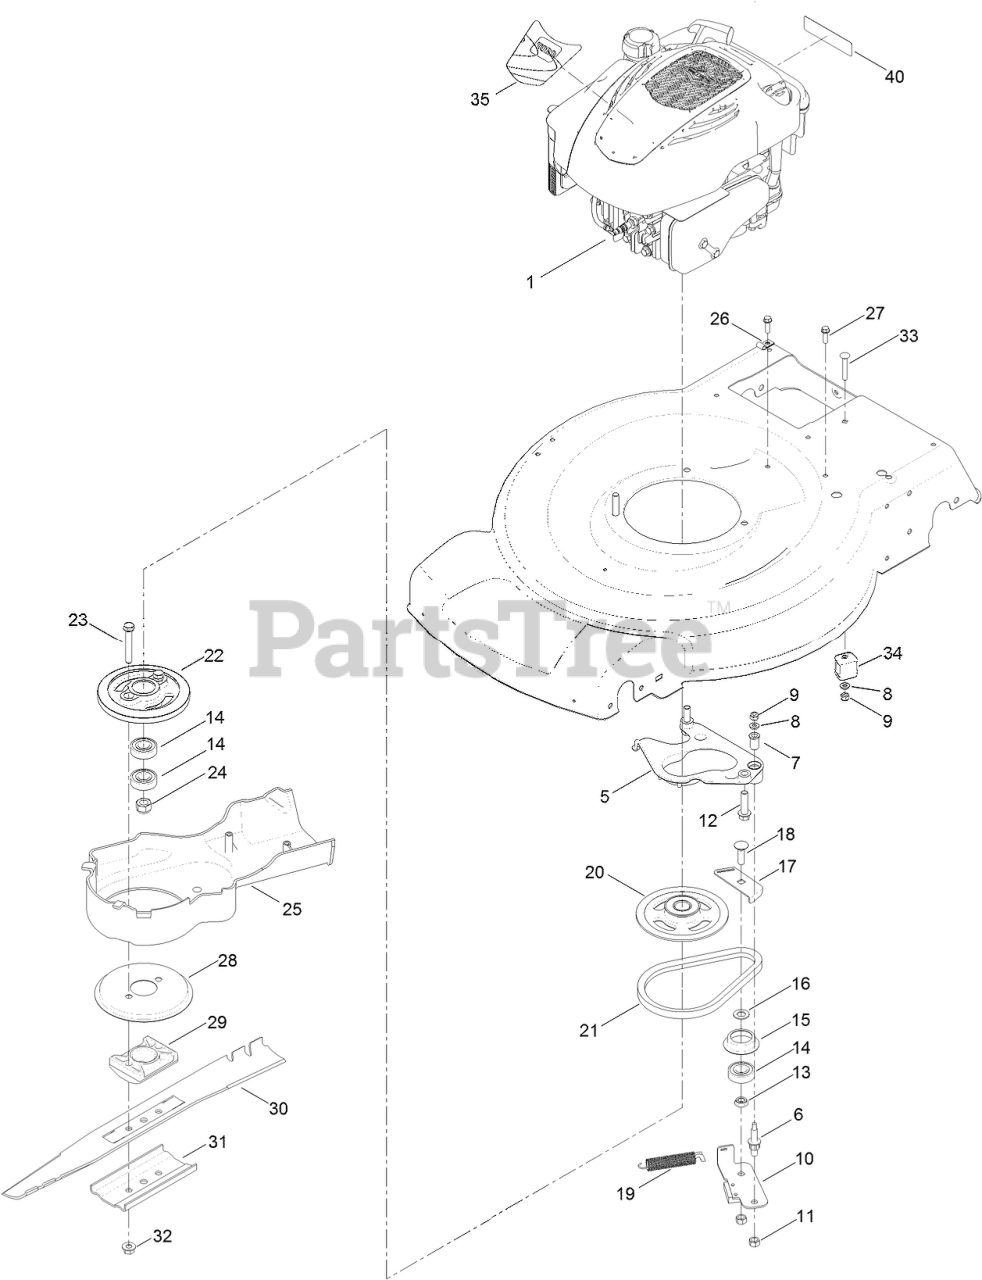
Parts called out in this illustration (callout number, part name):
5	PLATE-ANCHOR
6	BOLT-SHOULDER
7	BUSHING
8	WASHER-FLAT
9	NUT-LOCK, NI
10	PLATE-BRAKE
11	NUT-HEX
12	SCREW-HWH
13	SPACER-BEARING
14	BEARING-BALL
15	RETAINER-BELT
16	WASHER-PLAIN
17	PLATE-GUIDE
18	BOLT-CARR
19	SPRING-TENSION, BRAKE
20	PULLEY
21	BELT
22	DRUM
23	SCREW-HH
24	NUT-HEX
26	CLIP-CLOSED, INSULATED
27	SCREW-HWH
28	DISC
29	SUPPORT-BLADE
30	BLADE-22 INCH
31	SUPPORT-BLADE
32	NUT-FLANGE, LOCK
33	SCREW-CARR
34	ANCHOR-CABLE
35	DECAL-SHROUD
40	DECAL-ARRESTER, SPARK
